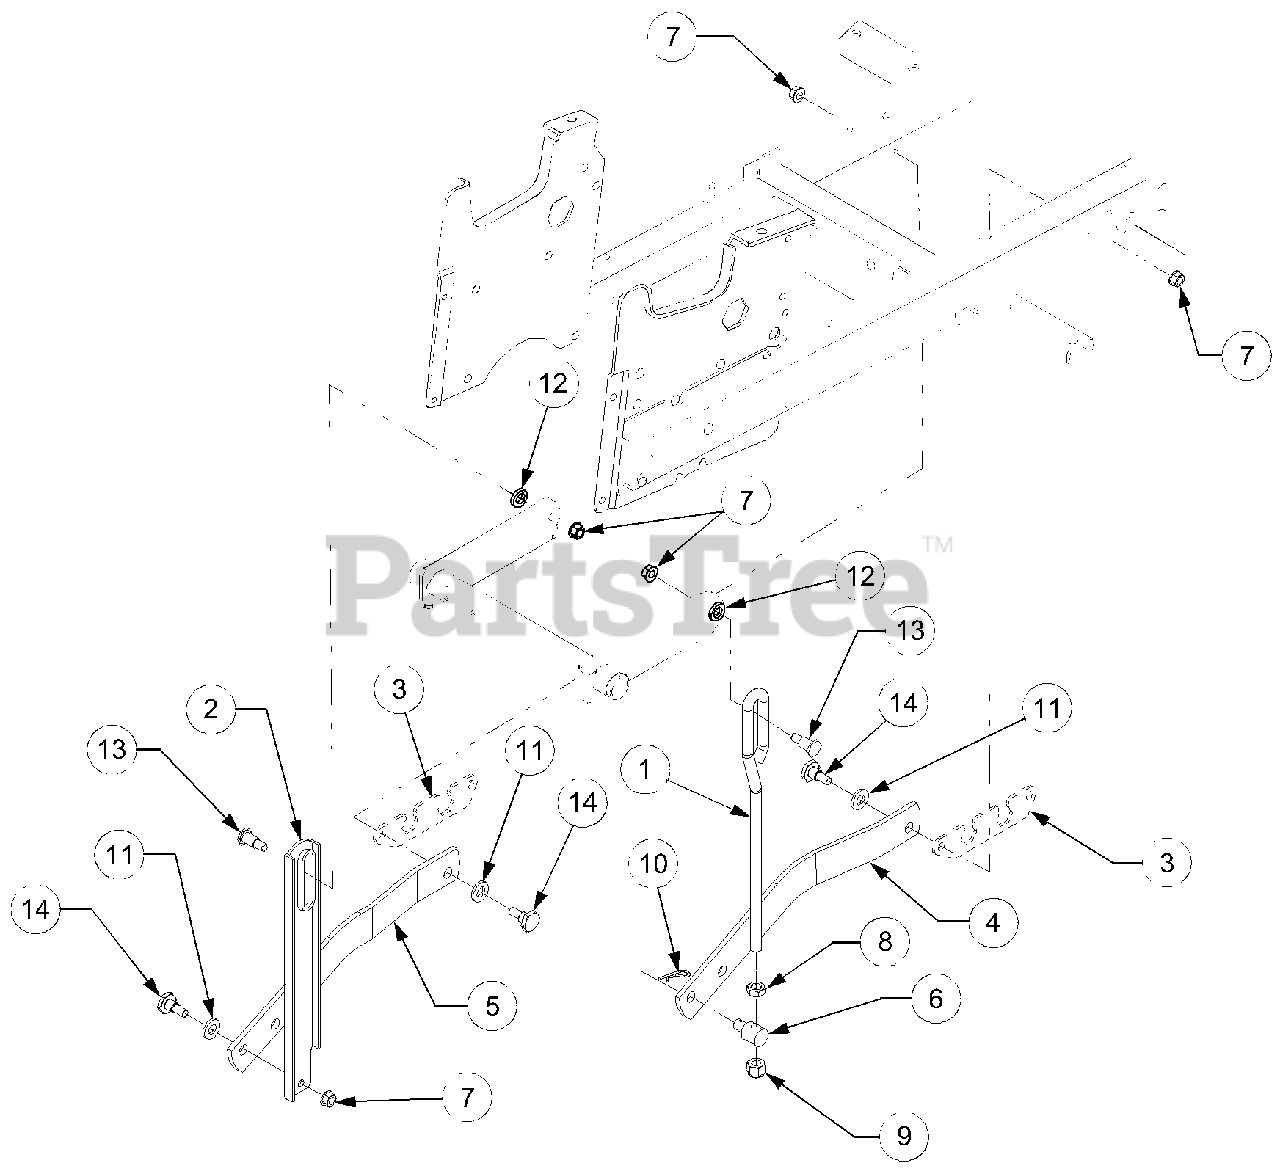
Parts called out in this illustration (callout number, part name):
1	Rod, Lift Link
8	Nut, Hex Flange Lock, 3/8-16
9	Nut, Hex Jam, 1/2-13 GR5
10	Nut, Hex Insert Lock, 1/2-13
11	Pin, Internal Cotter
12	Washer, Flat, .5 x 1.5 x .15
13	Washer, Flat, .531 x .875 x .15
14	Bolt, Shoulder
15	Bolt, Shoulder
